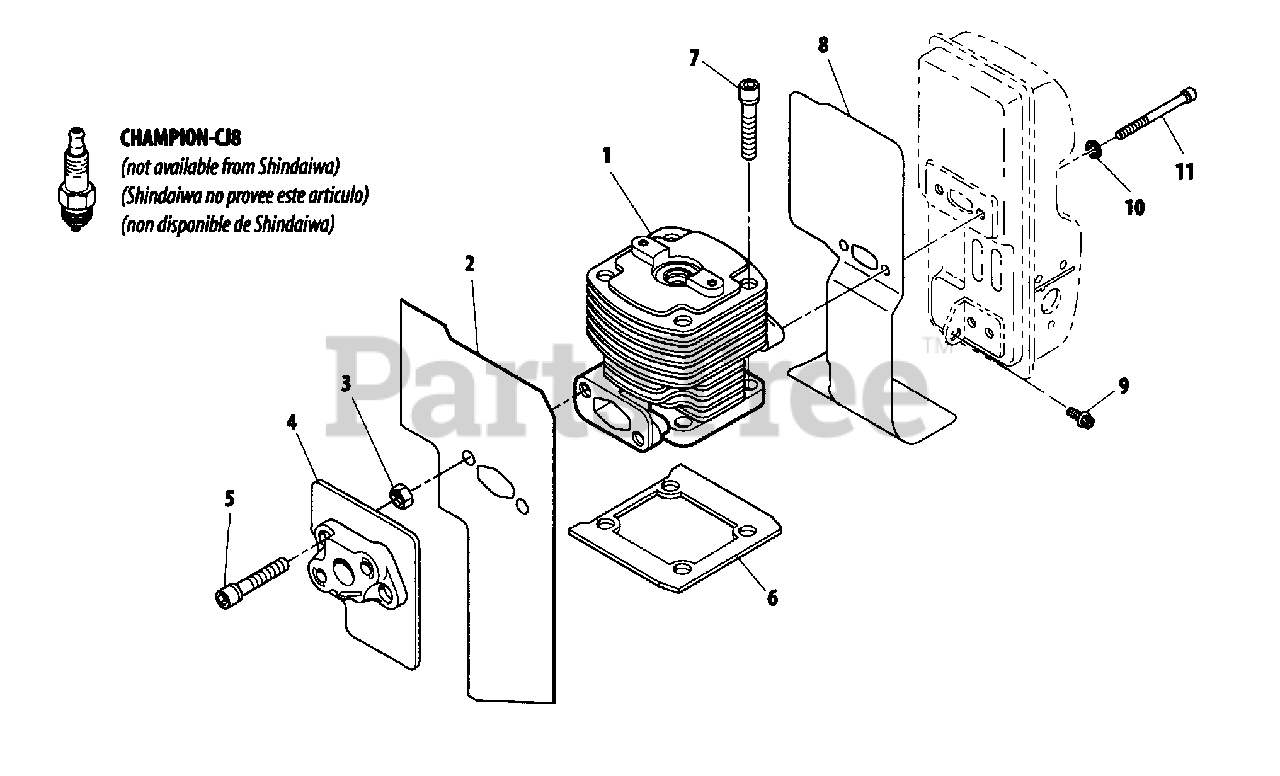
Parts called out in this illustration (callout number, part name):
1	CYLINDER
2	HEAT SHIELD, INTAKE
3	NUT M5×6.3
4	INSULATOR, INTAKE
5	BOLT
6	GASKET, CYLINDER
7	BOLT 5
8	HEAT SHIELD, EXHAUST
9	BOLT M5×12
10	WASHER 6.5×11.5×0.8
11	BOLT
